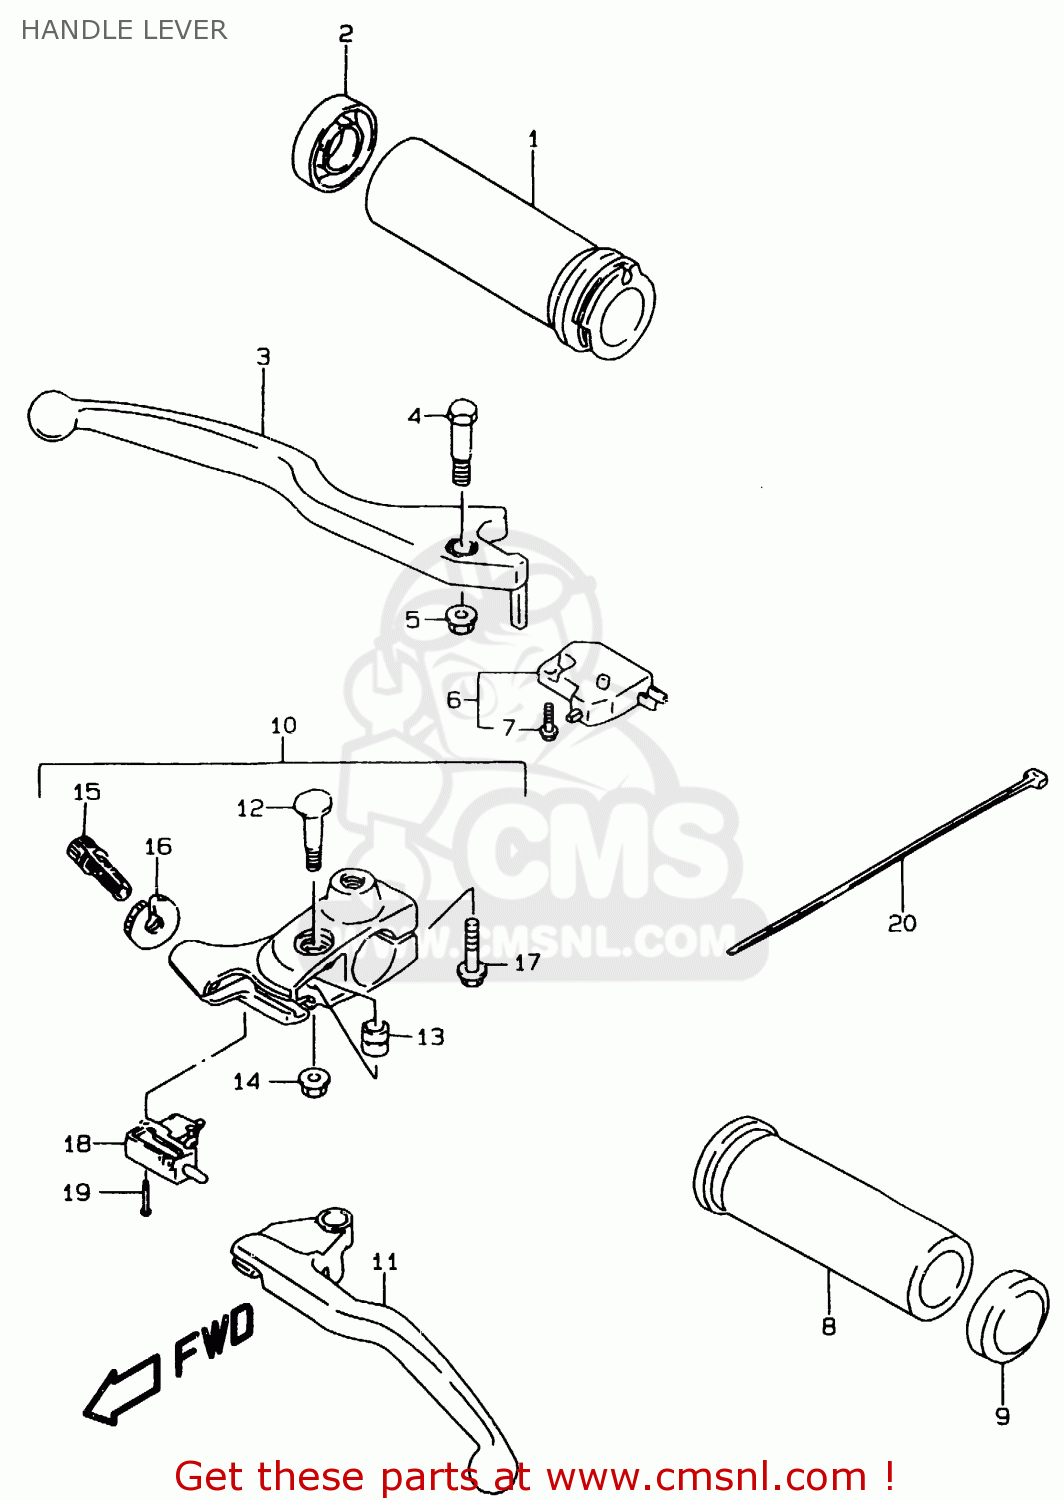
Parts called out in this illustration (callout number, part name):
1	GRIP,THROTTLE
2	CAP,GRIP END
3	LEVER,BRAKE
4	BOLT,LEVER SET
5	NUT 6MM
6	SWITCH ASSEMBLY,STOP
7	SCREW
8	GRIP,L
9	CAP,GRIP END
10	LEVER ASSY,CLUTCH
11	LEVER,CLUTCH
12	BOLT,CLUTCH LEVER
13	SPACER,CLUTCH LEVER PIVOT
14	NUT 6MM
15	ADJUSTER,WIRE
16	NUT,LOCK
17	BOLT
18	SWITCH,CLUTCH
19	SCREW
20	CLAMP
